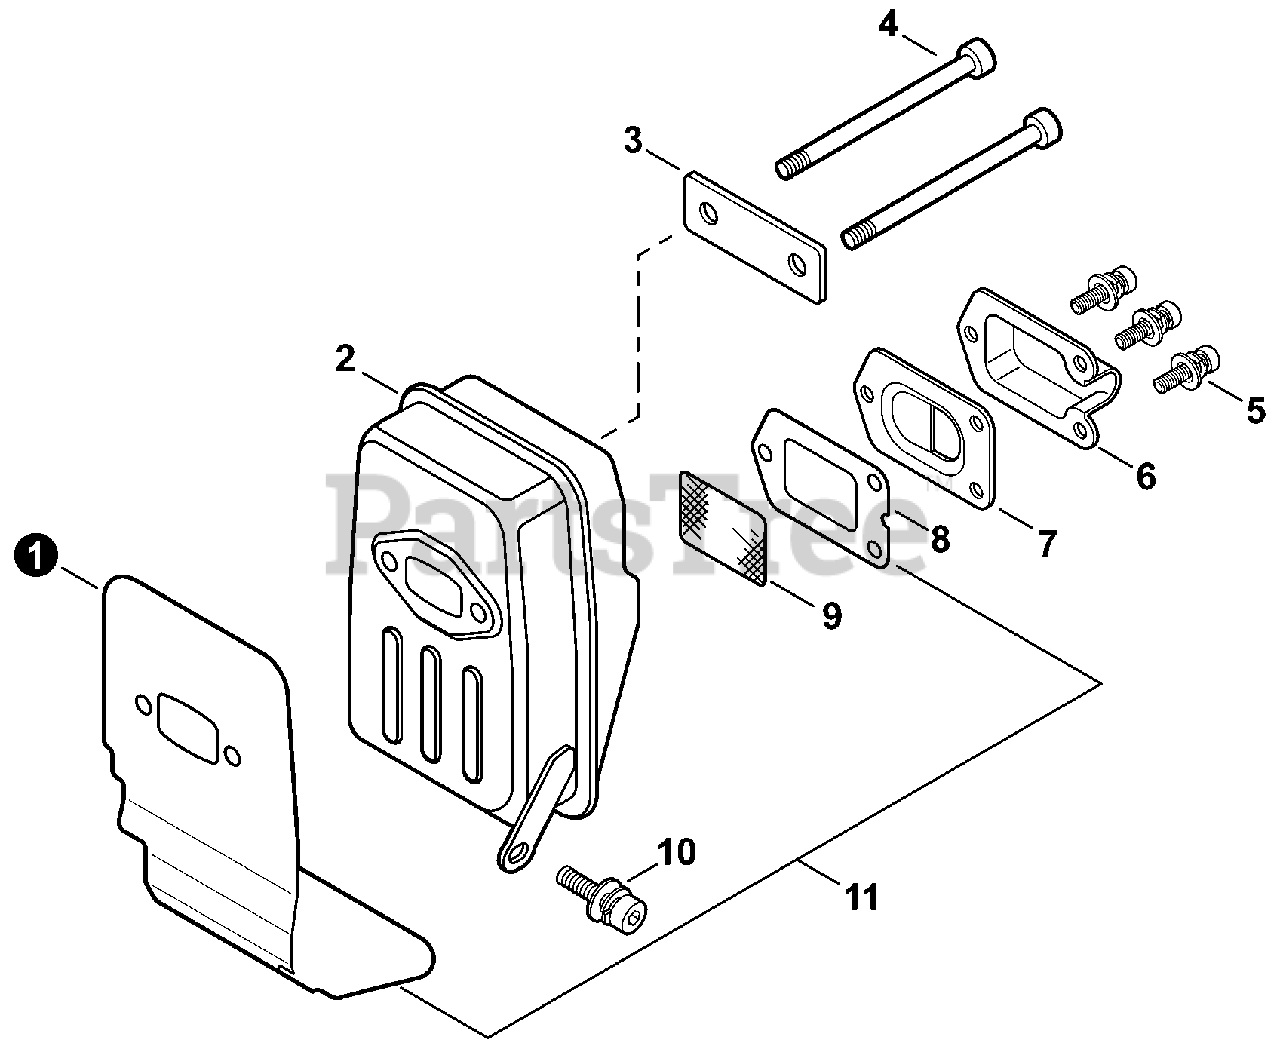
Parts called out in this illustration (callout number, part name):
1	HEAT SHIELD, EXHAUST
2	MUFFLER
3	PLATE, EYE
4	BOLT 6×60
5	SCREW 4×10
6	OUTLET, EXHAUST
7	GUIDE, EXHAUST
8	GASKET, EXHAUST
9	SCREEN, SPARK ARRESTER
10	BOLT 5×12
11	GASKET KIT
